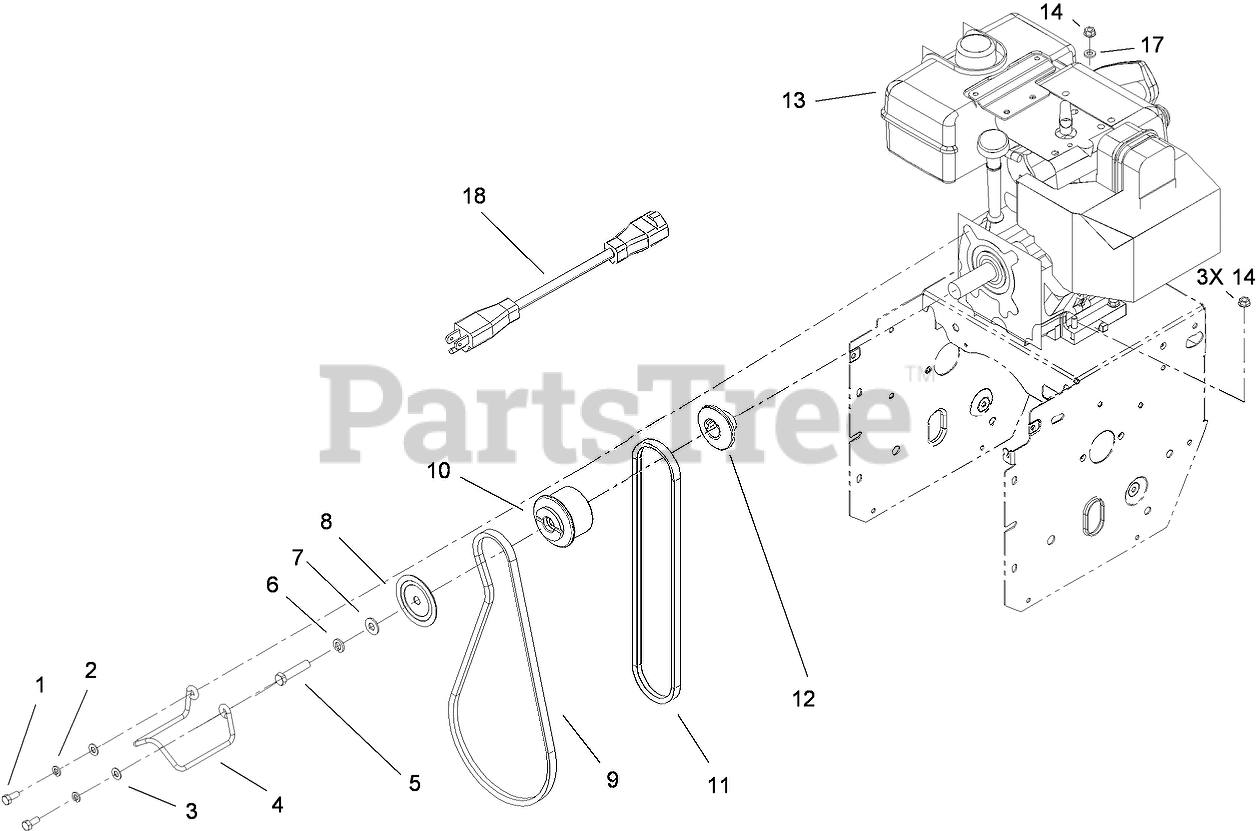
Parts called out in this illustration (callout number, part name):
1	SCREW-HH
2	WASHER-LOCK
3	WASHER-PLAIN
4	GUIDE-BELT
5	SCREW-HH
6	WASHER-LOCK
7	WASHER-FLAT
8	SHEAVE-HALF, IMPELLER
9	BELT-V
10	PULLEY-ENGINE, CENTER
11	V BELT-TRACTION
12	SHEAVE-HALF, TRACTION
13	ENGINE-TECUMSEH, LH358SA-159625A ES
14	NUT-HF
17	WASHER-FLAT
18	CORD-EXTENSION
